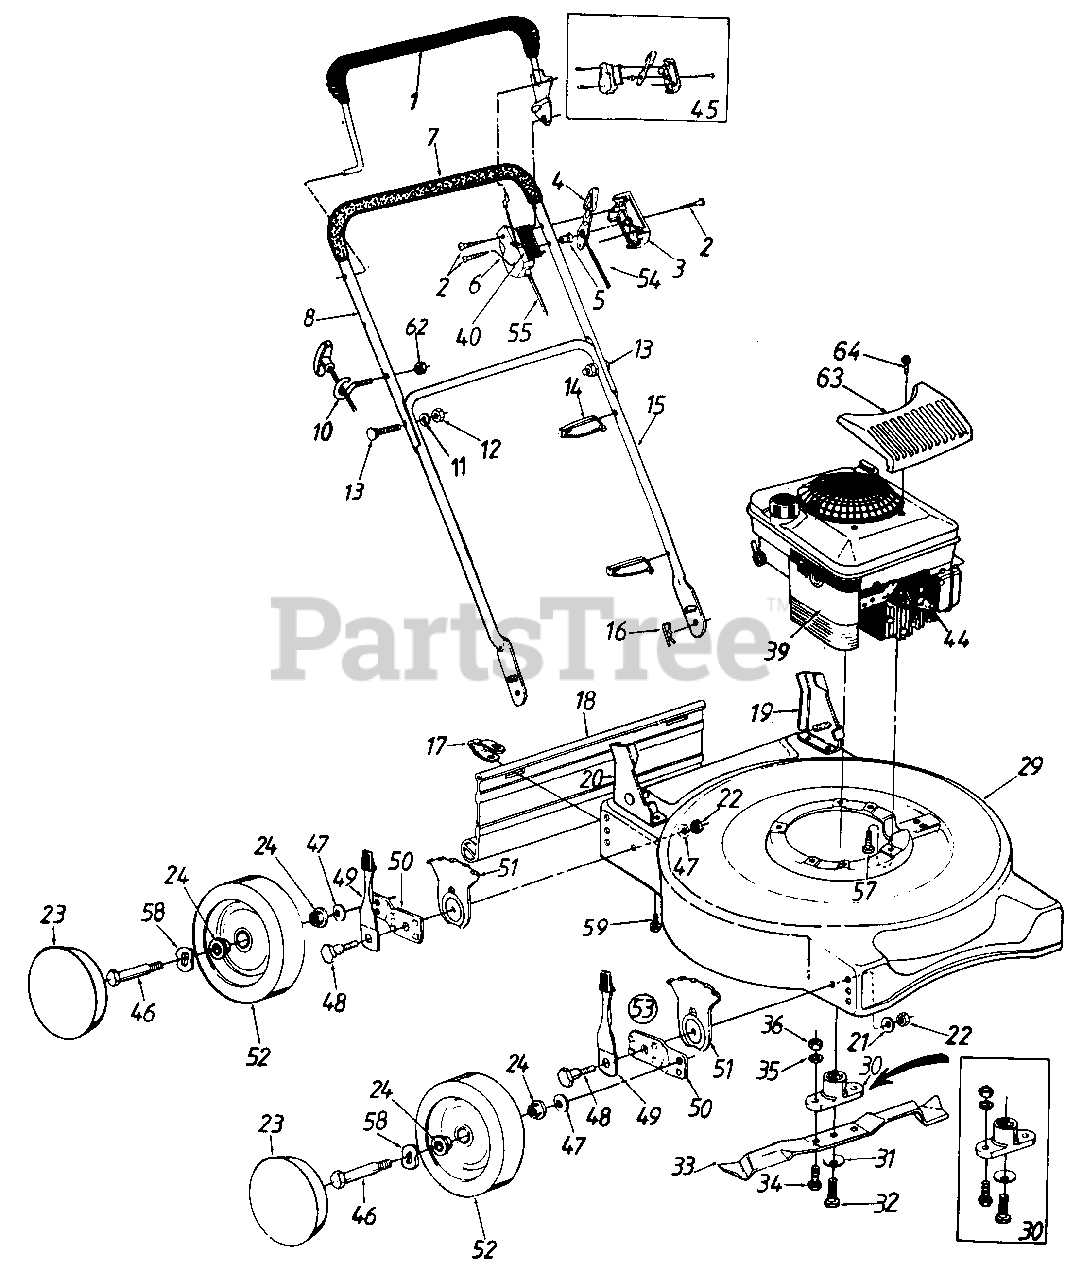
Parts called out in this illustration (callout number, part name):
2	SCREW-TRUSS MACH
3	PANEL HALF-CONTROL
4	LEVER-THROTTLE CONT-REV
5	PIN-CONTROL DISC
6	PANEL HALF-CLUTCH
7	GRIP-FOAM
8	HANDLE-UPPER
10	ROPE-GUIDE EYEBOLT
11	WASHER-LOCK-5/16
12	NUT-HEX 5/16-18
13	BOLT-CARRIAGE-CURV 5/16-18 X 1.38
14	TIE-CABLE
15	LOWER HANDLE
16	PIN-INTERN COT-5/16 DIA
17	CLIP-HINGE
18	FLAP-RR
19	BRACKET ASSY-HDLE
20	BRACKET ASSY-HDLE
21	WASHER-BELL .390 ID X 1.375 X .062
22	NUT-HEX 3/8-16
23	HUB CAP
24	BEARING-BALL
29	DECK ASSEMBLY-20IN MULCHING
30	WASHER-BELL
31	WASHER-BELL
32	SCREW-HEX 7/16-20 X 1.50
33	BLADE-20IN-MULCHING
34	SCREW-HEX 3/8-24 X 1 LG
35	WASHER-LOCK-3/8
36	NUT-HEX 3/8-24
44	INSULATOR-SPARK PLUG
45	KIT-THROTTLE CONTROL
46	SCREW-SHLD .498 DIA X 1.450
47	WASHER-BELL .400 ID X .88 X .060
48	SCREW-SHLD R
49	LEVER & KNOB ASSY
51	PLATE-HGT ADJ
52	WHEEL ASSY W/TIRE
53	ADJUSTER ASSY-HGT-RH
54	WIRE-THROTTLE-52 IN
55	CABLE-CONTROL
58	WASHER-WAVE .530 X .780 X .013
59	SCREW-HEX WASH HD 5/16-18X1/2
62	NUT-INS LOCK 1/4-20
63	COVER-ENGINE-QUANTUM
64	SCREW-TAP
